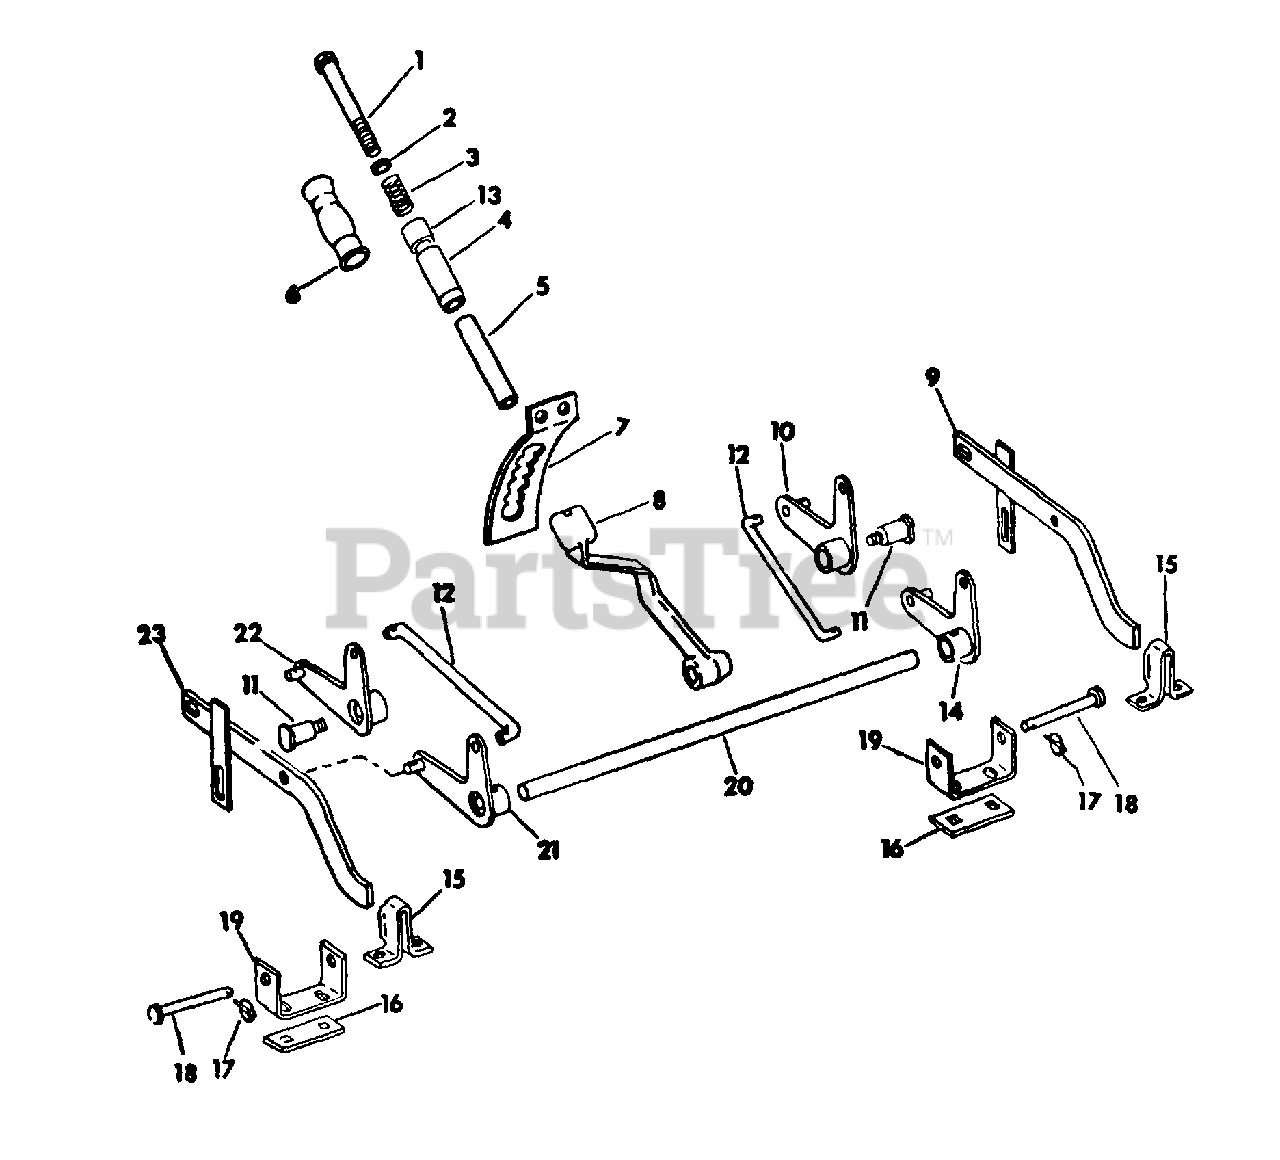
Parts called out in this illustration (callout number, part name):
1	SCREW 3/8-16 X 6-1/4 ZND HEX HD CAP
2	WASHER, SPRING RETAINING
3	SPRING, COMPRESSION
4	BUSHING, LIFT
5	BUSHING, LIFT HANDLE
6	GRIP, HANDLE
7	SECTOR, LIFT HANDLE
9	SUPPORT ASSY, RH LIFT BAR
10	ARM ASSY, RH FRONT LIFT
12	ROD, CONNECTING LINK
13	BUSHING, LIFT HANDLE
14	ARM ASSY, RH REAR LIFT
15	CHANNEL, LIFT BAR REAR GUIDE
16	PLATE, STIFFENER
17	PIN, KLIK
19	CLEVIS, LOCK PIN FRT BRACKET
21	ARM ASSY, LH REAR LIFT
22	ARM ASSY, LH FRONT LIFT
23	SUPPORT ASSY, LH LIFT BAR
